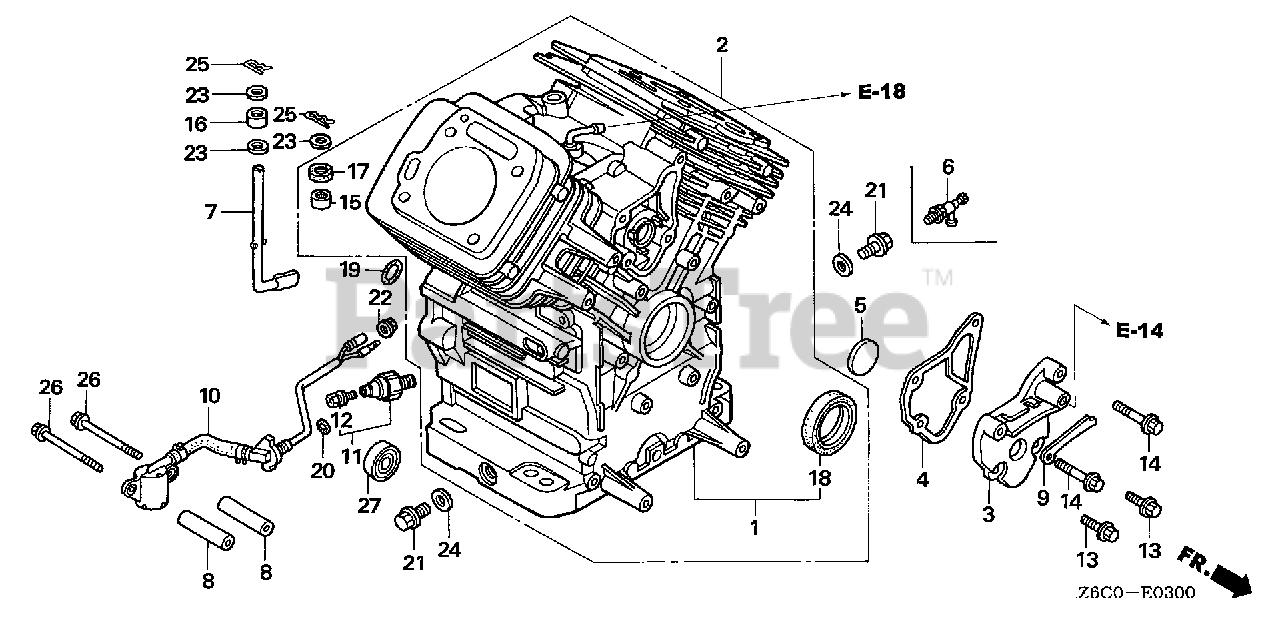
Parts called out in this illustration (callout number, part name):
2	CYLINDER ASSY.
3	COVER, BREATHER
4	GASKET, BREATHER COVER
5	VALVE, BREATHER
6	VALVE, DRAIN (14X1.5)
7	SHAFT, GOVERNOR ARM
8	COLLAR, FILTER SETTING
9	CLAMP, WIRE
10	SWITCH ASSY., OIL LEVEL
13	BOLT, FLANGE (6X16)
14	BOLT, FLANGE (6X32)
15	BEARING, NEEDLE (8X12.7X11.1)
16	BEARING, NEEDLE (8X12X10)
17	OIL SEAL (8X14X5)
18	OIL SEAL (38X58X9)
19	O-RING (13X3.0)
20	O-RING (14MM) (ARAI) Use up to Engine SN 2949254.
20	O-RING (14MM) (NOK)
21	BOLT, DRAIN PLUG (14MM)
22	NUT, FLANGE (10MM)
23	WASHER, PLAIN (8MM)
24	WASHER, DRAIN PLUG (14MM)
25	PIN, LOCK (8MM)
26	BOLT, FLANGE (6X75)
27	BEARING, RADIAL BALL (6003)
